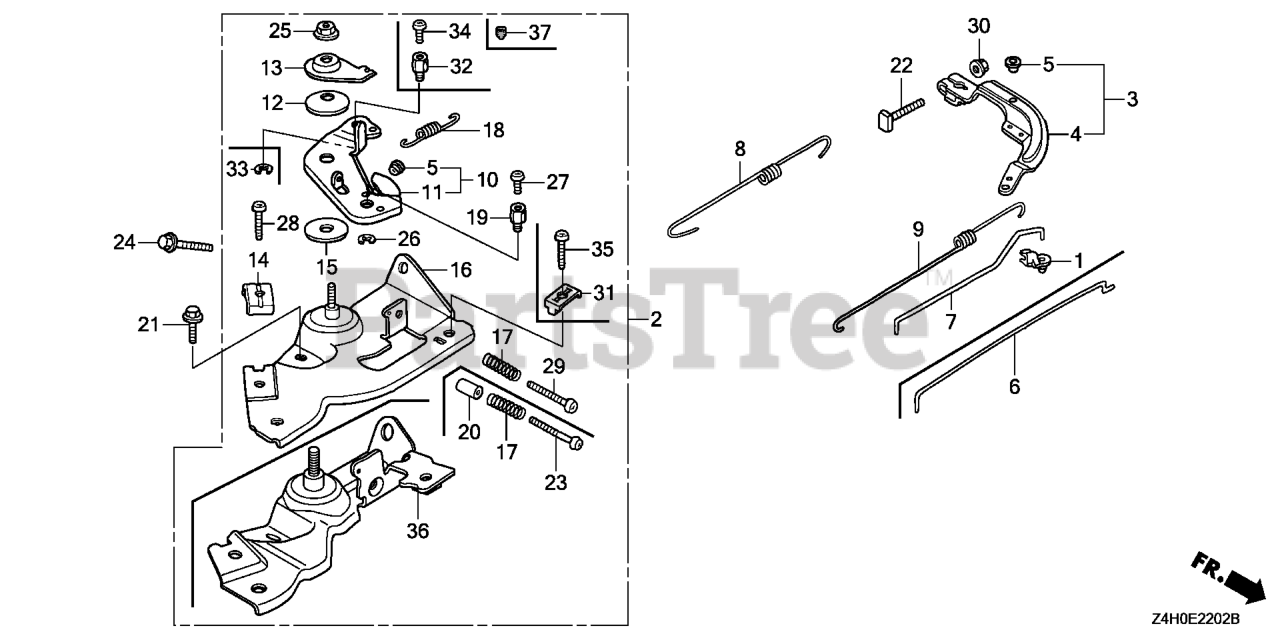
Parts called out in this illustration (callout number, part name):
2	CONTROL ASSY.
4	ARM, GOVERNOR
6	ROD, GOVERNOR
8	SPRING, GOVERNOR
9	SPRING, THROTTLE RETURN
11	LEVER, CONTROL
12	SPRING, LEVER
13	WASHER, CONTROL LEVER
14	HOLDER, CABLE
15	SPACER, CONTROL LEVER
17	SPRING, CONTROL ADJUSTING Use from Engine SN 2327377.
18	SPRING, CABLE RETURN
19	HOLDER, WIRE
20	COLLAR, STOPPER
21	BOLT, FLANGE (6X12) (CT200)
22	BOLT, GOVERNOR ARM
23	SCREW, RECESSED (5X25)
24	BOLT, FLANGE (6X20) (CT200)
25	NUT, SELF-LOCK (6MM)
26	CIRCLIP (5MM) Use from Engine SN 2327377.
27	SCREW, PAN (4X6)
28	SCREW, PAN (5X16)
30	NUT, FLANGE (6MM)
36	BASE, CONTROL
